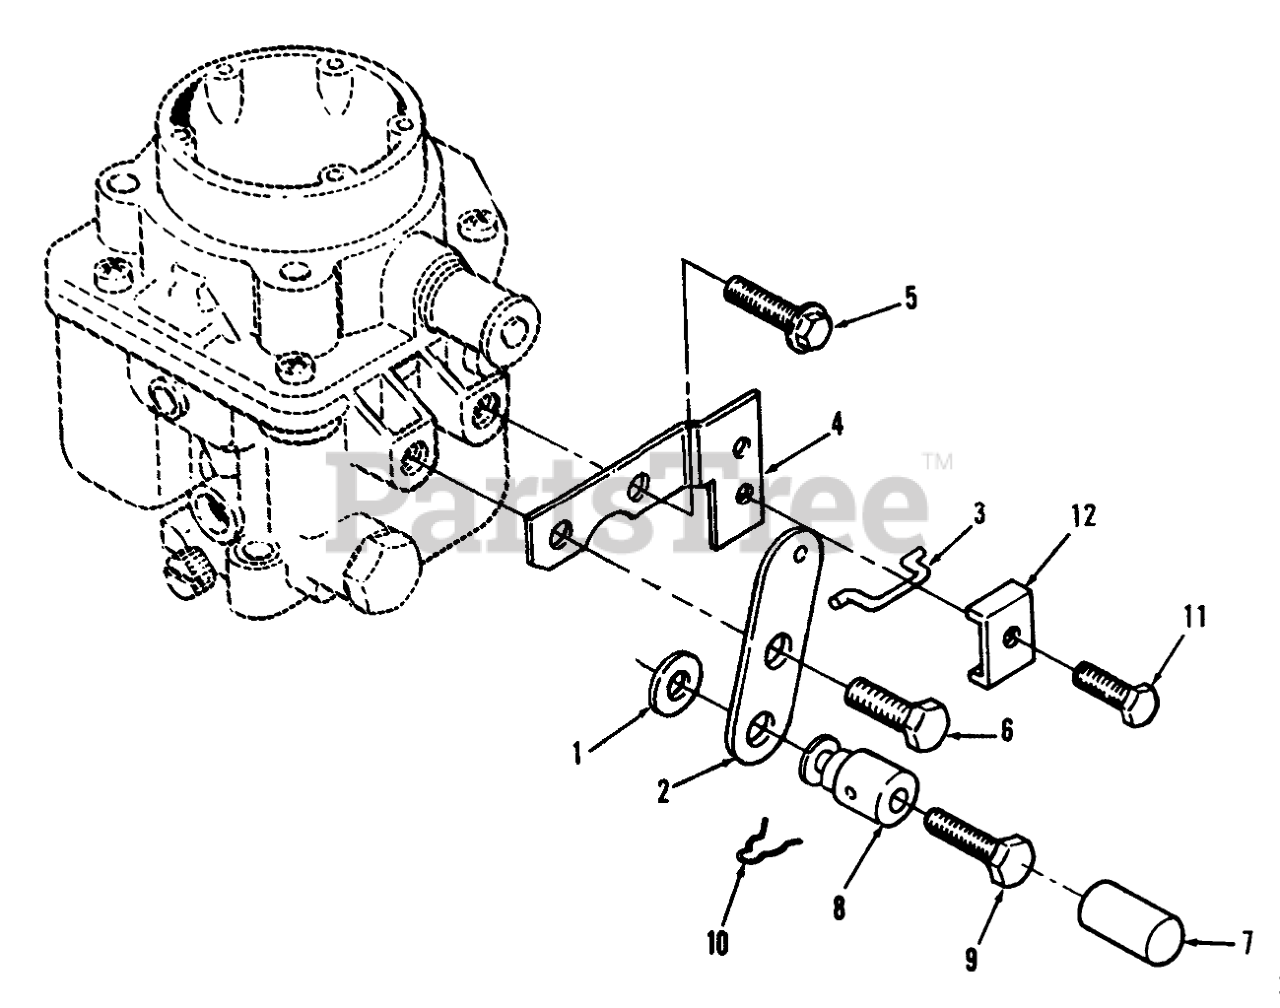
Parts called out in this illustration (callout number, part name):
1	Washer
2	SWIVEL-CHOKE
3	LINK-CHOKE
4	BRACKET
5	Bolt
6	MACHINE SCREW
8	SWIVEL
9	Bolt
10	PIN-COTTER
11	Bolt
